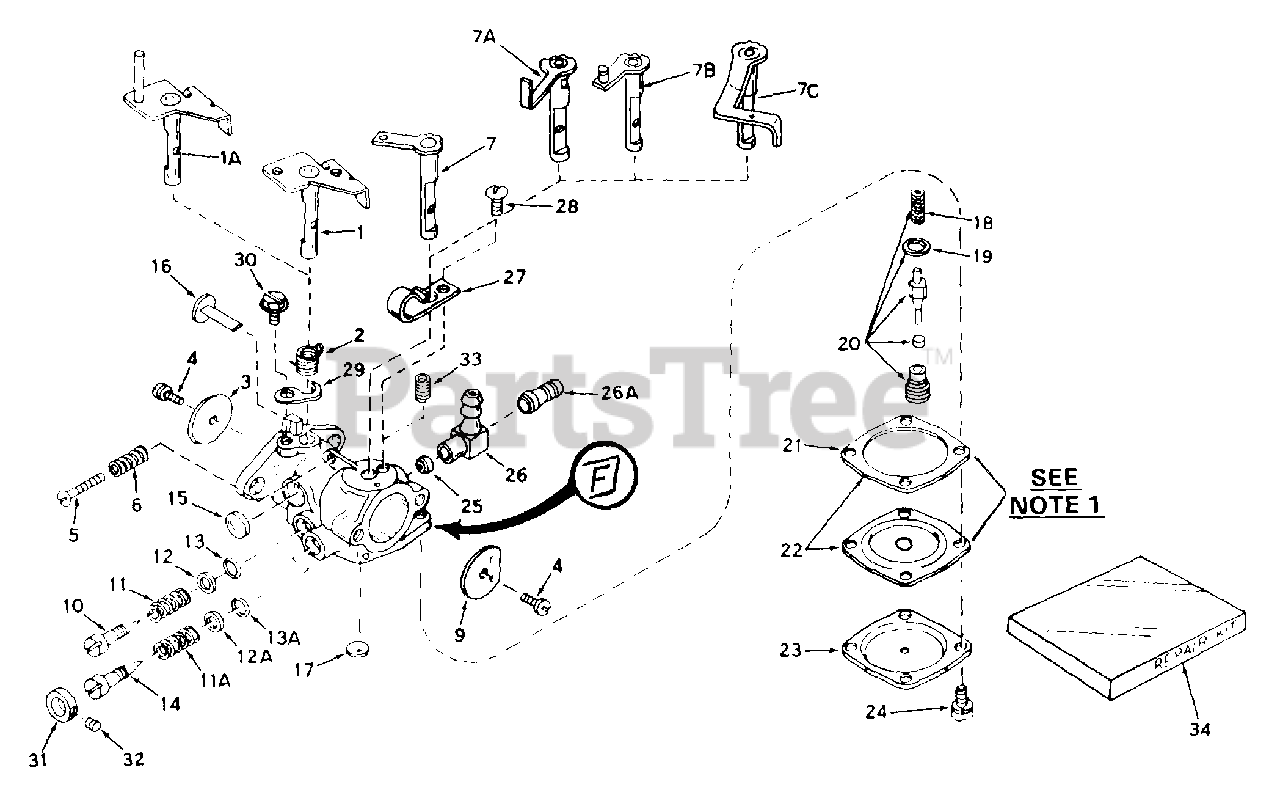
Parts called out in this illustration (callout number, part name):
1	"Shaft & Lever Assy., Throttle
2	Spring, Throttle return
3	Shutter, Throttle
4	Screw, Throttle & Choke shutter
5	Screw, Idle regulating
6	Spring, Idle speed screw
7B	Shaft & Lever Assy., Choke
9	Shutter, Choke
10	Screw, Idle adj.
11	Spring, Idle adj. screw
11A	Spring, Main adj. screw
12	Washer, Idle adj. screw
12A	Washer, Main adj. screw
13	"O" Ring, Idle adj. screw
13A	"O" Ring, Main adj. screw
14	Screw, Main adj. (.0225 dia. hole)
15	Plug, Welch
17	Plug, Welch
18	Spring, Valve
19	Gasket, Valve seat
20	Inlet Needle, Seat, Gasket & Spring A ssy.
21	Gasket, Diaphragm
22	Diaphragm Assy.
23	Cover, Diaphragm
24	Screw, Cover
26A	Fitting, Fuel inlet
27	Spring, Detent
28	Screw, Detent spring
29	Retainer, Throttle shaft
30	Screw, Retainer
34	Repair Kit
